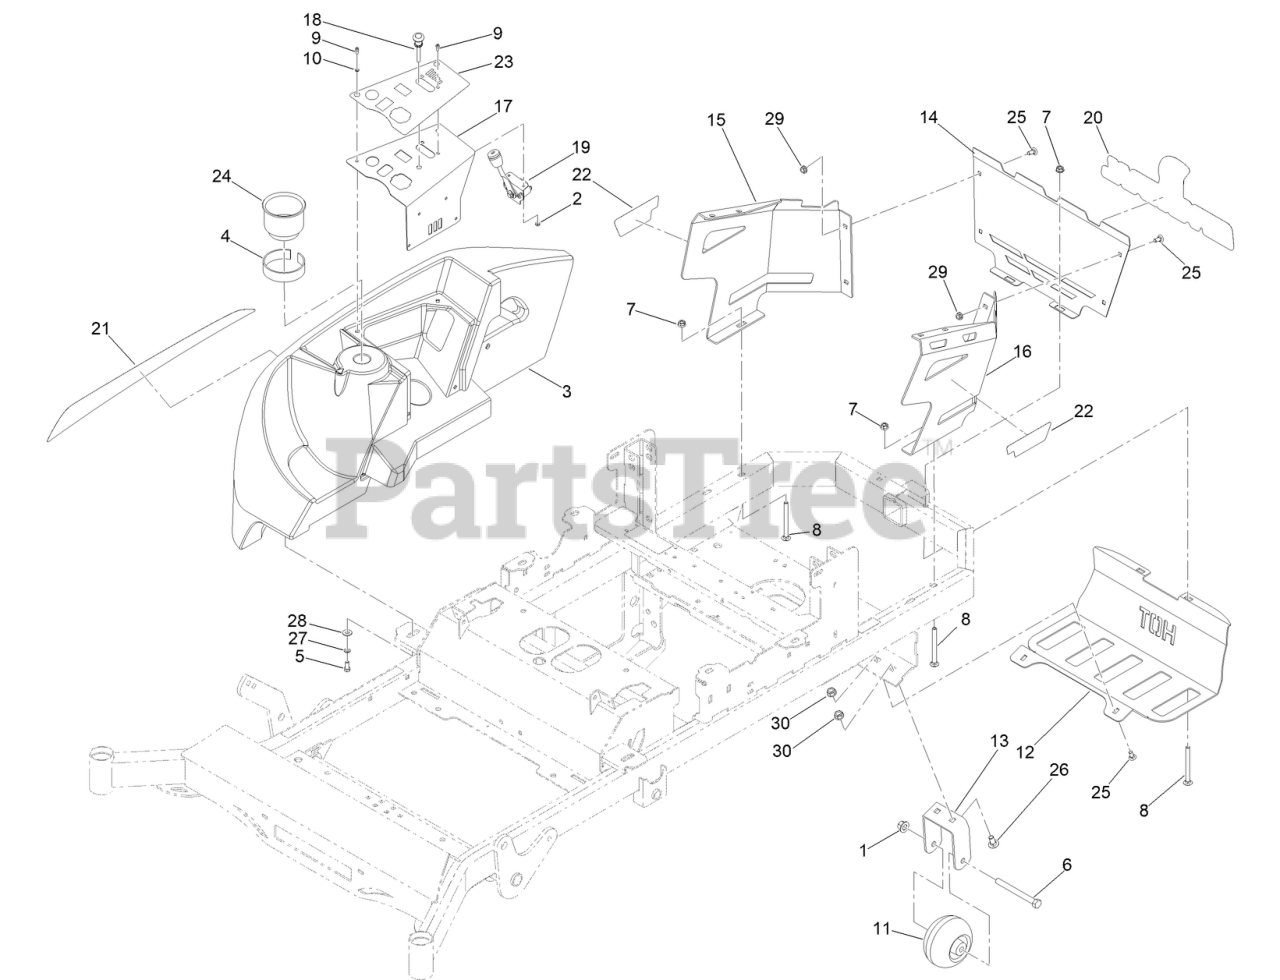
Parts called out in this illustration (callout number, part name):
1	NUT-LOCK
2	NUT-LOCK
3	CONSOLE W/ CUPHOLDER
4	TAPE-FOAM
5	SCREW-HH
6	SCREW-HH
8	3/8-16 X 4 CARRIAGE BOLT ZINC
9	10-24 X 1/2 SOCKET C/S 18-8 SS
10	#10 SPLIT LOCKWASHER 18-8 SS
11	MWR ANTI-SCALP WHL W/O GREASE FITTING
12	MWR MUFFLER GUARD PAINT
13	MWR STABILIZER MTG BRKT PAINT
14	PLATE - ENGINE COWLING
15	2021 RT/SRT ENGN COWLING RTPAINTED
16	2021 RT/SRT ENGN COWLING LT PAINTED
17	CONTROL PANEL BRKT INDIV CONTROLS PAINT
18	MWR CHOKE CABLE ASSM
19	KAWASAKI EFI THROTTLE
20	MWR RR SPARTAN LOGO
21	MWR FUEL TANK LOGO RT SIDE
22	SRT-XD MODEL DECAL
23	EFI KEYSWITCH CONSOLE DECAL
24	CUP HOLDER
25	BOLT-CARR
26	SCREW-CARR
27	WASHER-LOCK
28	WASHER-FLAT
30	NUT-HF
